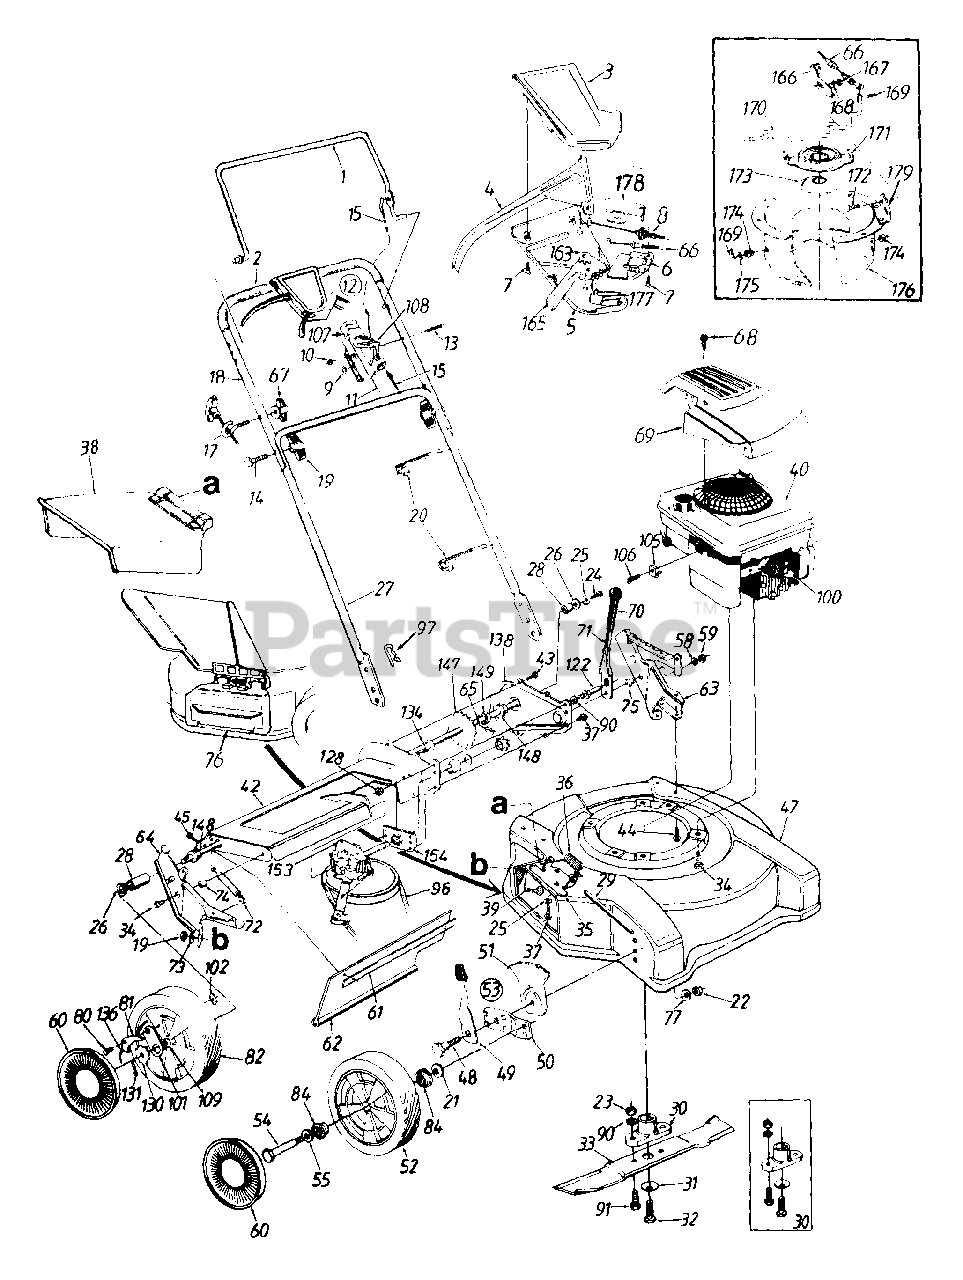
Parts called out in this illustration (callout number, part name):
2	Foam Grip
3	Upper - S.P. Control Cover
4	Control Lever
5	Lower - S.P. Control Cover
6	S P. Control Cover
7	Fl-"C"-Sunk Hd. Tap Scr. #10 x .75" Lg.
8	S.P. Adj. Cable - 48" Lg.
9	Spr. Wash 66" I.D.
10	Hex L-Nut 1/4-20 Thd.
11	Throttle Control Wire 55"
12	Throttle Box Comp.
13	Oval C-Sunk Scr.
14	Curved Carr Bolt 5/16-18 x 2" Lg.
15	Control Cable 39" Lg.
17	Rope Guide Bolt
19	Hand Knob 5/16-18 Thd.
20	Cable Tie
21	Bell-Wash..38" I.D. x .88"
22	Hex Nut 3/8-16 Thd.
23	Hex Nut 3/8-24 Thd.
24	Hex Bolt 1/4-20 x .62" Lg. (Grade 5)
25	Bell-Wash. 1/4" I.D.
26	Fl-Wash..531" I.D. x .93"
28	Spacer .513" I.D. x .703"
29	Hinge Pin
30	Blade Adapter Kit
31	Bell-Wash..46" I.D.
32	Hex Bolt 7/16-20 x 1.5" Lg.
33	22" Blade
34	Hex L-Wash. Hd. Scr. 3/8-16 x 1.0" Lg.
35	Adapter Plate
36	Torsion Spring
37	Hex Self-Tap Scr. 1/4-20 x .5"
38	Chute Deflector Ass'y.
39	Carriage Bolt 5/16-18 x .62" Lg.
40	Engine
44	Hex Wash. Hd. B-Tap Scr. 5/16-18
45	Hex AB-Tap Scr. 1/4 x .62"
49	Spring Lever Ass'y w/Knob
51	Height Adj. Plate
52	Front Wheel Ass'y. Comp.
53	Height Adj. Ass'y. Comp.- R.H
54	Shld. Bolt .498" Dia. x 1.45"
55	Wave Wash..51" I.D. x .75"
58	Fl-Wash..385" I.D. x .87"
59	Hex Patch L-Nut 3/8-24 Thd.
60	Hub Cap
61	Retaining Strip
62	Rear Flap
63	L.H Handle Wheel Brkt. Ass'y.
64	R.k. Handle Wheel Brkt. Ass'y.
65	#48 Chain 5" Pitch x 30 Links
66	6 Spd Cable .53" Lg.
67	Wing Nut 1/4-20 Thd.
68	Hi-Lo Scr #8-18 x 1.25" Lg.
69	Engine Shroud
71	Height Adj. Lever
72	Ext. Spring 5" O.D. x 3.8" Lg.
73	Bell-Wash 5/16" I.D.
74	Spacer .383" I.D. x 503"
75	Shld Spacer .5" Dia.
76	Mulching Plug
77	Bell-Wash .39" I.D. x 1.38" O.D.
80	Shld Scr .342" Dia. x .268"
81	Pawl
82	Rear Wheel Ass'y Comp.
84	Ball Bearing 1/2" I.D.
90	L-Wash 3/8" I.D.
91	Hex Bolt 3/8-24 x 1.0" Lg.
96	"V"-Belt
97	Hairpin Clip
100	Spark Plug Boot
101	Pawl Plate
102	Weld L-Nut 1/4-20 Thd.
105	Cable Clamp
106	Hex Self-Tap Scr #10-32 x .62"
107	Throttle Body
108	Throttle Lever
109	Sleeve Brg. 1/2" I.D.
122	Shld Pin 3/8-24 x 1.43" Lg.
128	Hex Jam Nut 3/8-24 Thd.
130	Ratchet Wheel 1.62" O.D.
131	Cotter Pin 1/8" Dia.
134	Hex Flange Bearing
136	Spring - Nylon
148	Hex Flange Bearing
149	Fl-Wash..531" I.D. x .93"
153	Transmission Comp
163	Rack Gear Insert
165	6 Spd. Shift Lever
168	Bell-Wash..265" I.D. x .75" O.D.
169	Cotter Pin 3/32" Dia. x .75" Lg.
170	Shift Rod
171	Movable Pulley Half Ass'y.
172	Carr. Bolt 1/4-20 x .5" Lg.
173	Pulley Half
174	Flanged Bushing
175	Fl-Wash..328" I.D. x .68" O.D.
176	6 Spd. Housing Ass'y.
177	Shift Lever Spring
178	Rack Cable Bracket
179	Cable Mounting Bracket
